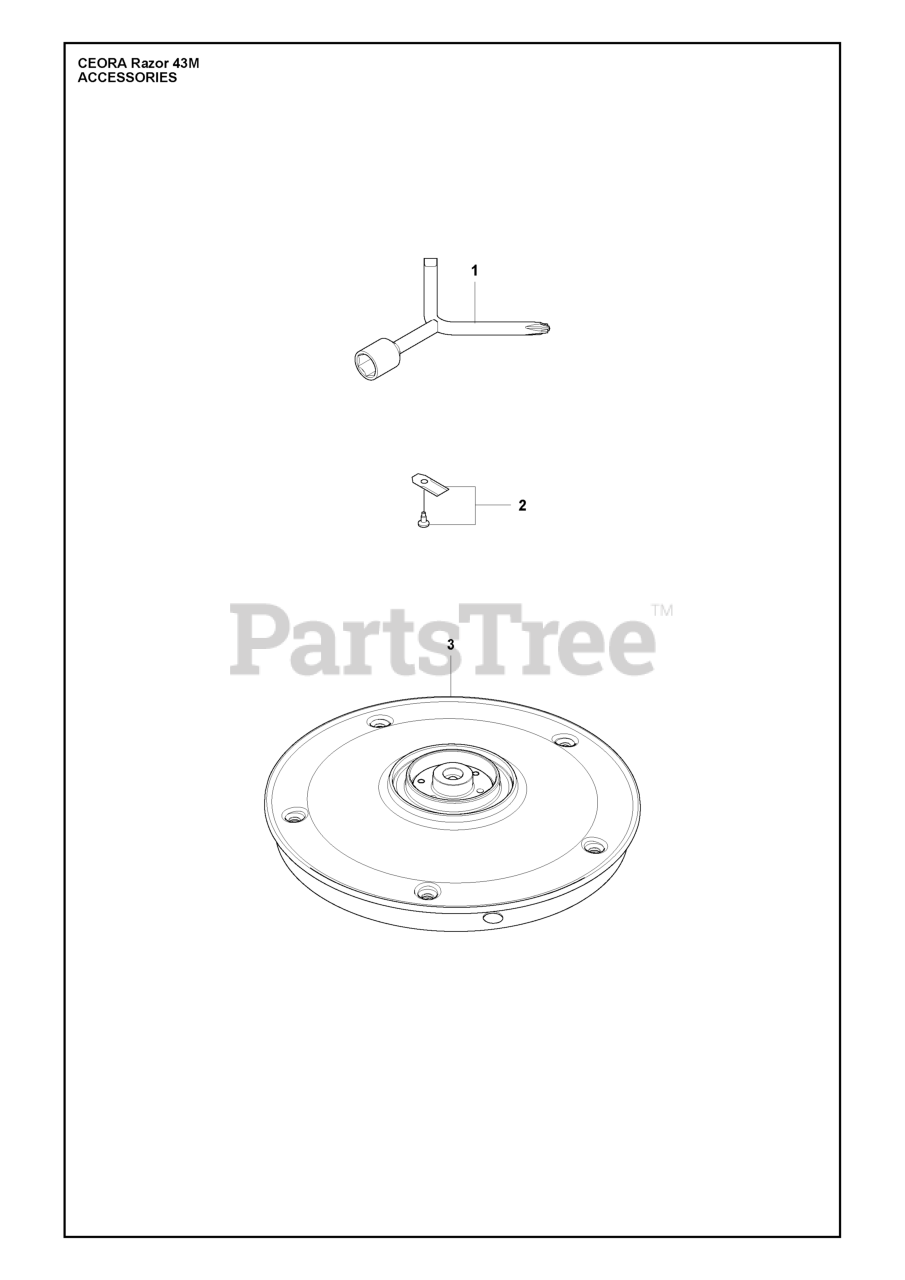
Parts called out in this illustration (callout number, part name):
2	HUS BLADE SET 300 PCS
2	HUS BLADE SET 9 PCS
2	HUS BLADE SET 45 PCS
